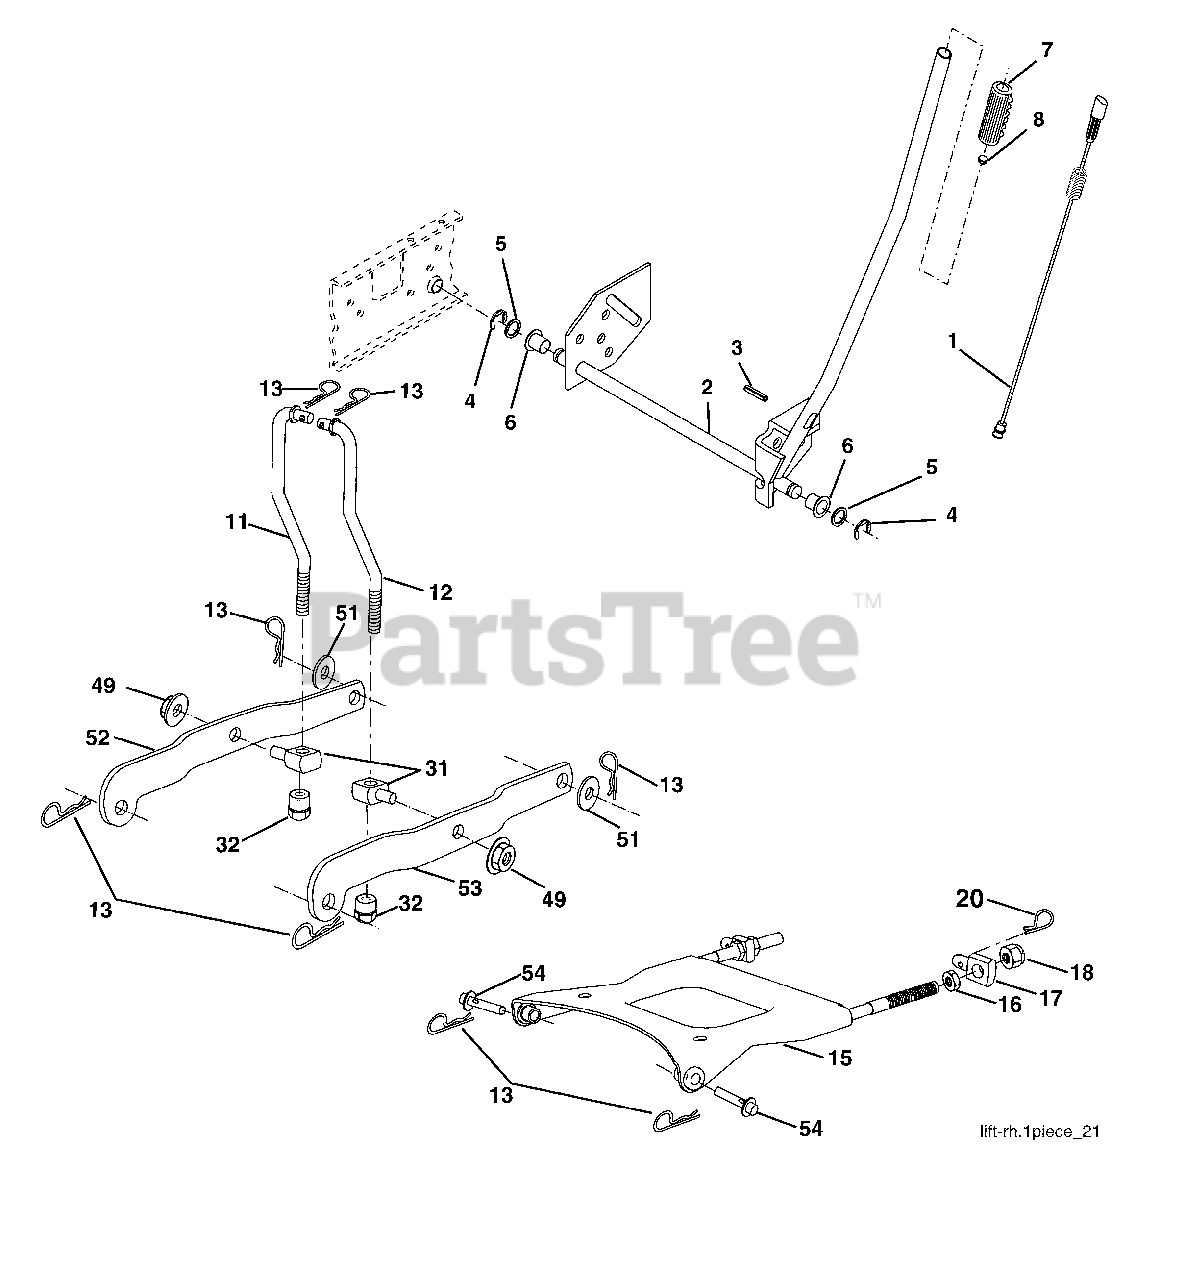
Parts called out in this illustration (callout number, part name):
1	Wire Asm Inner W/plunger 17 32
2	Shaft Asm Lift LH Inf Hgt P/L
3	Pin Groove 1 500 Zinc
4	E Ring #5133-62
5	Washer 21/32 x 1 x 21 Ga.
6	Bearing Nylon Blk 629 Id
7	Grip Handle
8	Button Plunger
11	Link Lift LH
12	Link Lift RH
13	Retainer Spring
15	Plate Asm Suspension Front
16	Nut Jam Hex 1/2-13 unc
17	Trunnion Blk Zinc
18	Nut Lock W/wsh 1/2-13 unc
20	Retainer Spring
31	Trunnion Suspension Arm
32	Nut Lift Link 7/16-20
49	Nut Hex Flange Lock
51	Washer 17/32 x 7/8 x 16 Ga.
52	Arm Suspension Rear LH
53	Arm Suspension Rear RH
54	Pin Flange
